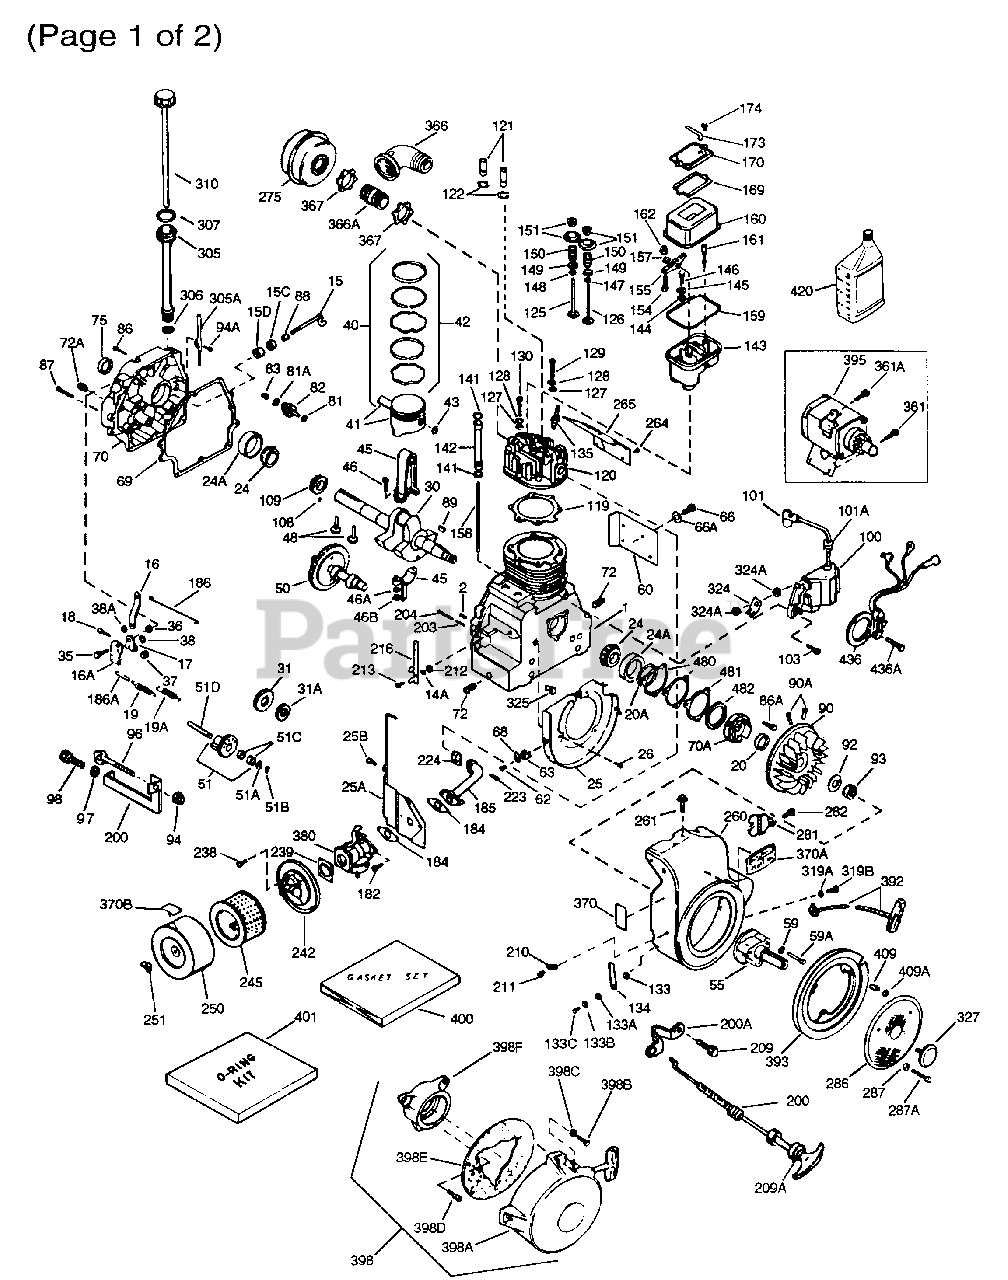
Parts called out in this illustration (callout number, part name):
1	"Cylinder (Incl. 2, 20, 72 & 72A)
2	Dowel Pin
15	Governor Rod
16B	Governor Spring Plate
17	Governor Lever Clamp
18	Screw, Torx T-25, 10-24 x 7/8"
19	Extension Spring
20	* Oil Seal
20A	* "O" Ring
24	Tapered Roller Bearing
24A	Bearing Cup
25	Blower Housing Baffle
25A	Air Baffle
25B	Screw, 1/4-20 x 5/8"
26	Screw, 1/4-20 x 5/8"
30	Crankshaft
35	Screw, 10-32 x 1/2"
37	Lock Nut, 10-24
38	Retaining Ring
40	Piston, Pin & Ring Set (Std.)
40	Piston, Pin & Ring Set (.010" OS)
40	Piston, Pin & Ring Set (.020" OS)
41	Piston & Pin Ass'y (Std.) (Incl. 43)
41	Piston & Pin Ass'y (.010" OS) Incl. 4 3
41	Piston & Pin Ass'y (.020" OS) Incl. 4 3
42	Ring Set (Std.)
42	Ring Set (.010" OS)
42	Ring Set (.020" OS)
43	Piston Pin Retaining Ring
45	Connecting Rod Ass'y (Incl.46 - 46B)
45	Connecting Rod Ass'y (.010" US) Incl. 46-46B
45	Connecting Rod Ass'y (.020" US) Incl. 46-46B
46	Connecting Rod Bolt
48	Valve Lifter
50	Camshaft (MCR)
51	Counterbalance Weight (Incl. 51)
51A	Thrust Washer
51B	Retaining Ring
51C	Needle Bearing
51D	Counterbalance Shaft
60	Blower Housing Extension
66	Screw, T-30, 1/4-20 x 1/2"
69	* Cylinder Cover Gasket
70	Cylinder Cover Incl. 15D,72,72A & 75
70A	Cylinder Cover (See Ref. #'s 480-482)
72	Oil Drain Plug
72A	Oil Drain Plug
75	Oil Seal
82	Governor Gear Ass'y
83	Governor Spool
86	Screw, 1/4-20 x 2-1/4"
86A	Screw, 5/16-18 x 7/8"
87	Screw, 1/4-20 x 1"
89	Flywheel Key
90	Flywheel (Incl. 90A)
90A	Trigger Pin Kit
92	Washer
93	Flywheel Nut
94A	Screw, 10-24 x 7/8"
100	Solid State Ignition
101	Spark Plug Cover
101A	Grommet
103	Screw, 1/4-20 x 3/4"
108	Pin, Crankshaft gear
109	Crankshaft Gear
119	* Cylinder Head Gasket
120	Cylinder Head
121	Valve Guide Kit (Incl. 2 of 122)
122	Retaining Ring
125	Exhaust Valve (Std.) (Incl. 151)
125	Exhaust Valve (1/32" OS) (Incl. 151)
126	Intake Valve (Std.) (Incl. 151)
126	Intake Valve (1/32" OS) (Incl. 151)
128	Belleville Washer
129	Screw, 5/16-18 x 1-3/4"
130	Screw, 5/16-18 x 1-3/8"
135	Resistor Spark Plug (RN4C) also avail able in Packaged Part #740069
141	* "O" Ring (Also Incl. in 401)
142	Push Rod Tube
143	Rocker Arm Housing
144	* "O" Ring (Also Incl. in 401)
146	Screw, 1/4-20 x 29/32"
147	* "O" Ring (Also Incl. in 401)
148	* "O" Ring (Also Incl. in 401)
149	Valve Spring Cap
150	Valve Spring
151	Valve Spring Keeper
154	Screw, 1/4-20 x 3/4"
155	Rocker Arm
157	Retaining Ring
158	Push Rod
159	* "O" Ring (Also Incl. in 401)
160	Rocker Arm Housing
161	Rocker Arm Stud
162	Nut, 1/4-20
169	* Valve Cover Gasket (Also Incl.in 401)
170	Breather Body
173	Breather Tube
174	* Screw, 10-32 x 5/8" Also Incl. in 40 1
182	Screw, Torx T-30, 5/16-18 x 1-1/8"
184	* Carburetor To Intake Pipe Gasket
185	Intake Pipe
186	Governor Link
203	Compression Spring
204	Screw, 10-24 x 2"
210	Conduit Clip
211	Screw, 10-32 x 3/8"
212	Bushing
213	Screw, 10-24 x 5/8"
216	R.P.M. Adjusting Lever
216	Control Lever
223	Screw, Torx T-30, 5/16-18 x 7/8"
238	Screw, 10-32 x 5/8"
239	* Air Cleaner Gasket
245	Air Filter
250	Air Cleaner Cover
251	Wing Nut, 1/4-20
260	Blower Housing
261	Screw, 1/4-20 x 7/16"
261A	Screw, 1/4-20 x 7/16"
264	Screw, 10-16 x 3/8"
286	Starter Screen
287	Lockwasher
287A	Screw, 1/4-20 x 1-1/2"
305	Oil Fill Tube
305A	Oil Fill Tube Extension
307	"O" Ring
310	Dipstick
319A	Lock Washer
319B	Screw, 5/16-24 x 3/8"
324	Terminal
324A	Nut, 8-32
355	Starter Handle
361	Screw, 5/16-18 x 11/16"
361A	Screw, 5/16-18 x 1/2"
370	Instruction Decal
370A	Decal - XL/C Industrial/Commercial
370B	Decal - Important Lubrication - SAE 3
380	Carburetor (Incl. 184)
392	Starter Rope
393	Starter Rope Pulley
395	Electric Starter Motor (12 Volt)
400	* Gasket Set (Incl. items marked PK in notes) Incl. part #'s 29673 (1), 3010 2 (2), 31950 (2), 31956B (1), 31958A (1), 31971 (2), 31972 (1), 32031 (1), 32599 (1), 33476A (2), 33481 (4), 33 484 (3), 33487 (1), 33509 (1), 33515A (1), 34225A (1), 34302A
401	* "O" Ring Set (Also Incl. in 400) 3010 2 (2), 31958A (1), 33481(4), 33484 (3 ), 33487 (1), 33509 (1) 34410 (1)
420	SAE 30 4-Cycle Engine Oil (Quart)
480	* Shim Gasket (.004/.005) See Repair M anual
481	* Shim Gasket (.005/.007) See Repair M anual
482	* Steel Spacer (.010) See Repair Manua l
